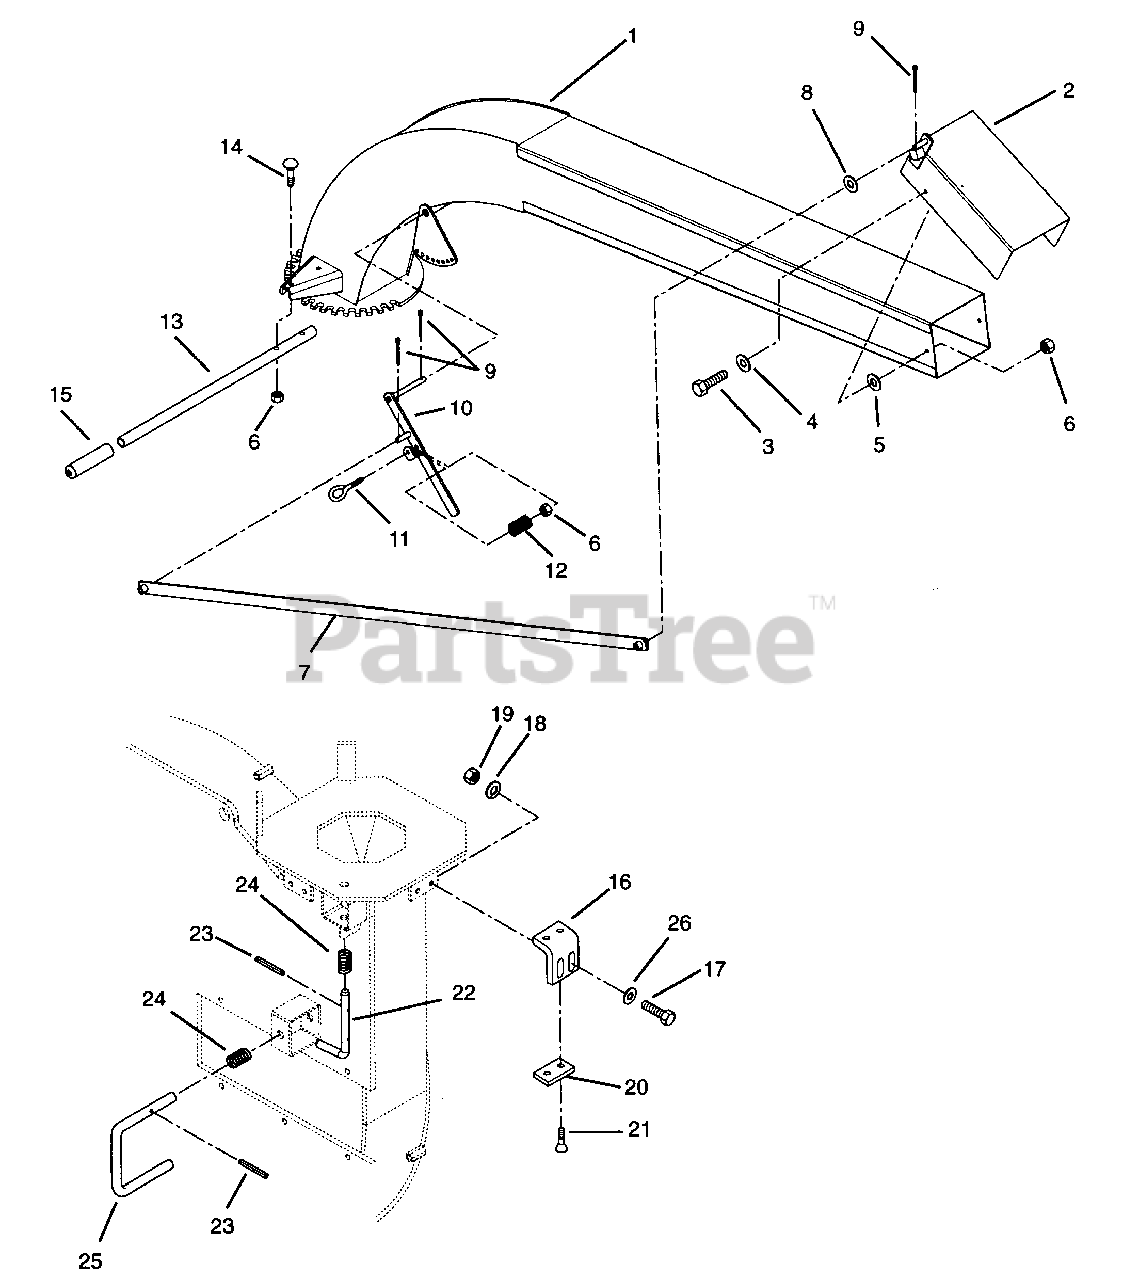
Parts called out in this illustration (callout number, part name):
1	Discharge Chute Weldment
2	Bonnet Weldment
3	Bolt-Hex .38-16 x 1.00 Grade 5
4	Washer-Flat-Steel .438 x 1.0 x .083
5	Washer-Flat-Nylon .38 x 1.0 x .083
6	Nut-Locking .375-16
7	Control Lever Weldment
8	Washer-Flat-Steel .505 x .880 x .720
9	Pin-Cotter .12 x 1.0
10	Adjustment Handle Weldment
11	Eye Bolt .375-16 x 2.50
12	Spring-Compression .045 x .50 x 1.187
13	Rotation Handle
14	Bolt-Round Head Square Neck .38-16 x 1.50Grade 5
15	Handle Grip
16	Adjustment Angle
17	Bolt-Hex .50-13 x 1.25 Grade 5
18	Washer-Lock .50 Reg.
19	Nut-Locking Nylon .50-13 Grade 5
20	Wear Pad
21	Screw-Socket Head .25-20 x .50
22	Pin Index
23	Pin-Roll .188 x 1.50
24	Spring-Compression .080 x .91 x 3.38
25	Flywheel Lock Pin
26	Washer-Flat-Steel .531 x 1.062 x .095
